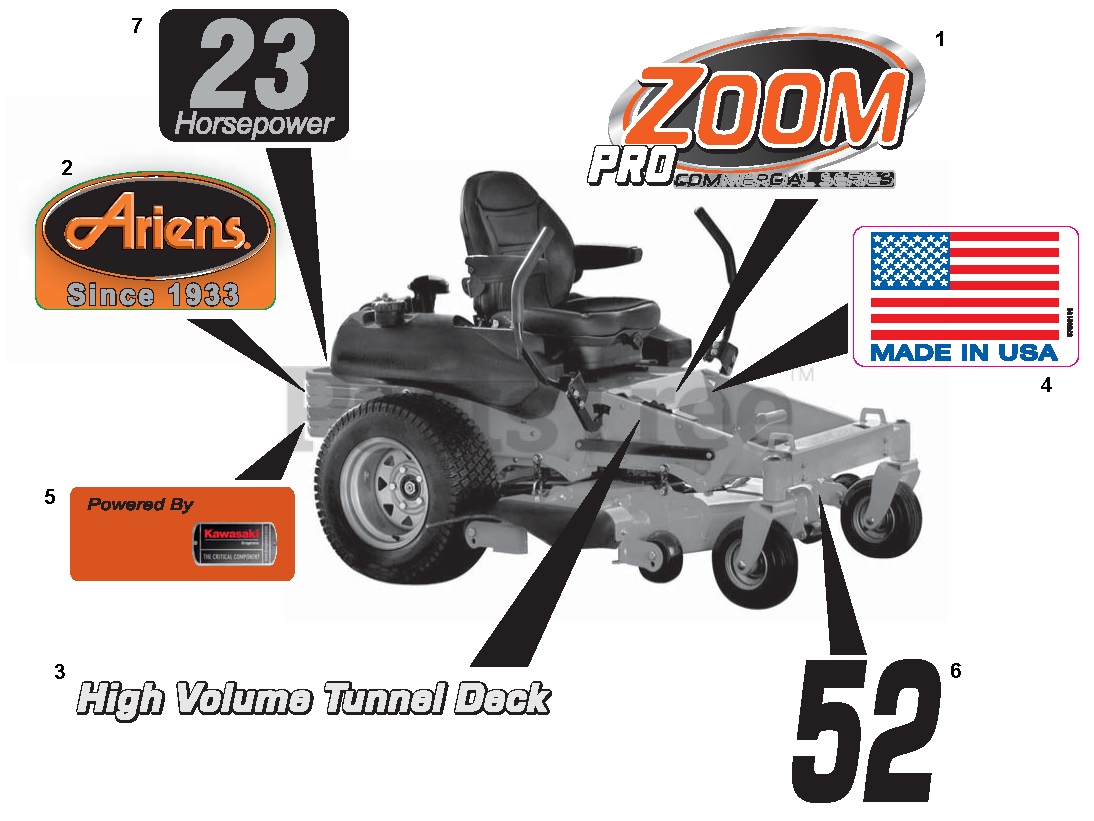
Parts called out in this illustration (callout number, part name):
1	DECAL, ARIENS PROZOOM 3.75"
2	DECAL-ARIENS SINCE 1933
3	DECAL, DECK FEATURES
4	DECAL,MADE IN USA/FLAG
5	DECAL, POWERED BY KAWASAKI
6	DECAL, "52" (PROZOOM DECK)
7	DECAL, 23 HP
